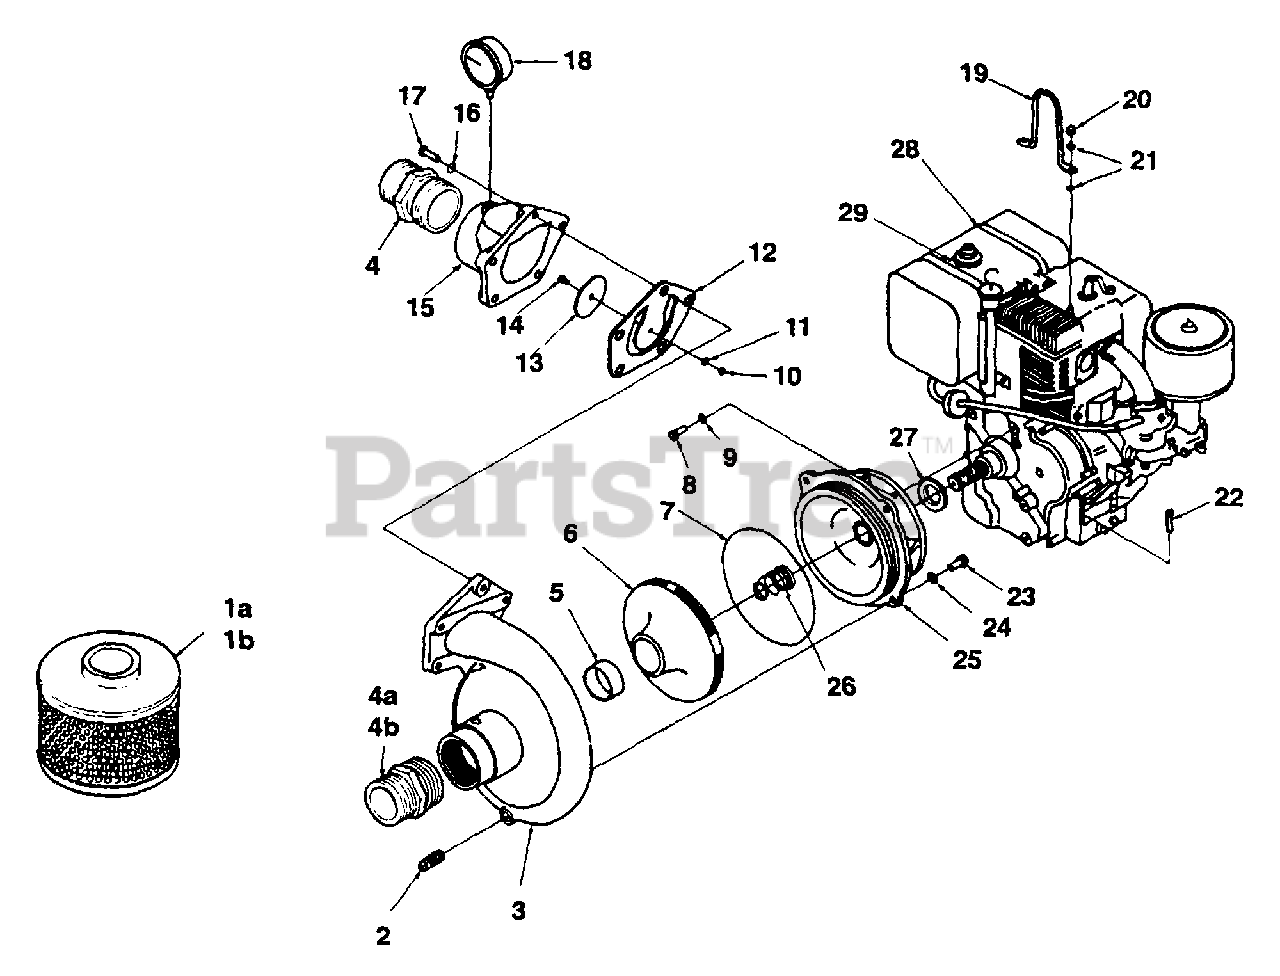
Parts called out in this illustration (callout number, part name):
1A	STRAINER
1B	STRAINER
2	PLUG - Drain
3	PUMP BODY
4A	NIPPLE
4B	NIPPLE
5	BEARING
6	IMPELLER
7	"O" RING
8	SCREW - Hex Hd. (3/8-16 x 1)
9	WASHER - Flat (3/8)
10	NUT - Hex (12-24)
11	WASHER - Flat (#12)
12	VALVE - Flapper
13	WEIGHT - Valve
14	SCREW - Hex Hd. Mach (12-24 x 5/8)
15	BODY - Valve
16	WASHER - 3/8 Collar
17	SCREW - Socket Hd. (3/8-16 x 2)
18	GAUGE - Pressure
19	EYE - Lifting
20	NUT - Hex (5/16-18)
21	WASHER - Flat (5/16)
22	SCREW - Cap Hex Hd (5/16-18 x 1 3/4)
23	SCREW - Cap Hex Hd. (1/2-13 x 1)
24	WASHER - Flat (1/2)
25	HOUSING - End
26	SEAL - Shaft
27	SLINGER
28	FUEL TANK
29	CAP - Tank
